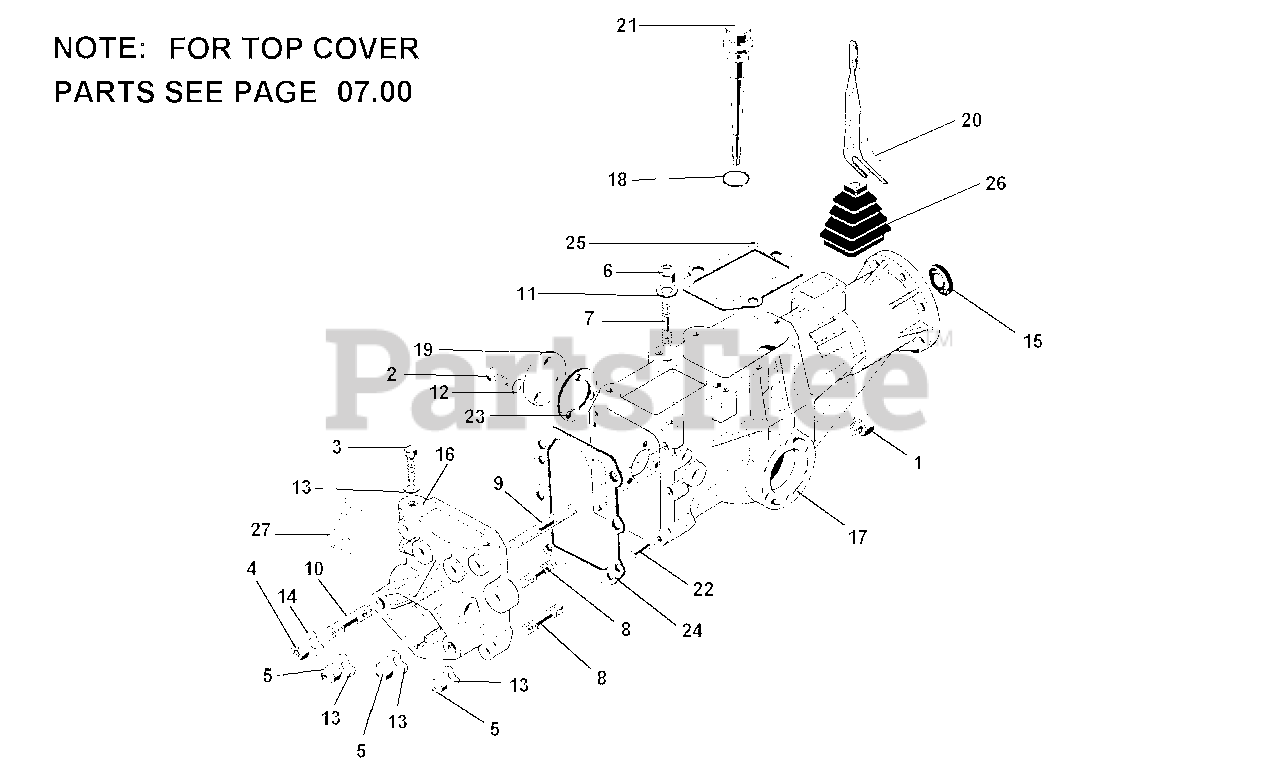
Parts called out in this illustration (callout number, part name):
1	PLUG 1/4 GAS
2	SCREW TE M6 X 10 UNI 5739 5S
3	SCREW M8 X 20
4	NUT M12 X 1.25 UNI 5587 6S
5	NUT, SELF LOCKING M8
7	STUD M8 X 38 X 14 X 20
8	STUD M8 X 46 X 16 X 16
9	STUD M8 X 58 X 16 X 16
10	ST.56XM12X1.25X26XM12X22 8G
11	SUPER WASHER 8 DIN 6796
12	WASHER, LOCK 6.4
13	WASHER, LOCK 8.4
14	WASHER, LOCK 13
17	GEARBOX 745 / 606-605
18	RUBBER RING
20	CLUTCH LEVER
21	CAP, WITH MEASURING ROD
22	PARALLEL PIN D 6 X 20
24	GASKET, COVER
25	GASKET, COVER
